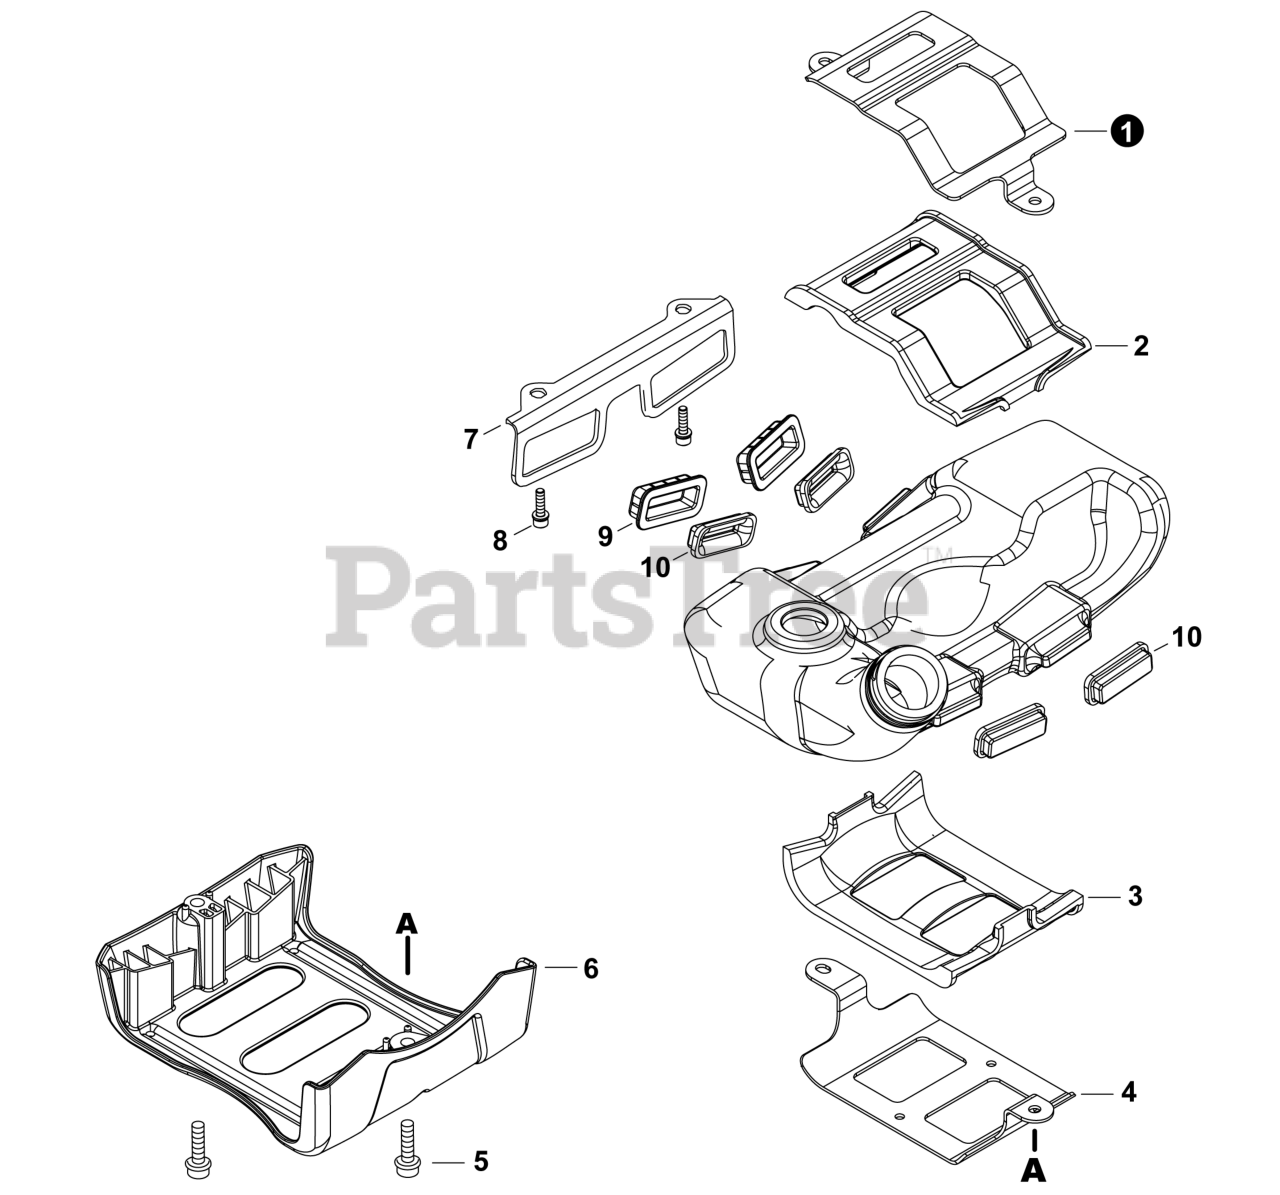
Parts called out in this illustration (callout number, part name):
1	BRACKET, FUEL TANK - UPPER
2	CUSHION, FUEL TANK - UPPER
3	CUSHION, FUEL TANK - LOWER
4	BRACKET, FUEL TANK - LOWER
5	BOLT, TORX 5x20
6	GUARD, FUEL TANK
7	BRACKET, FUEL TANK
8	BOLT, TORX 5x16
9	HOLDER, CUSHION
10	CUSHION, FUEL TANK
